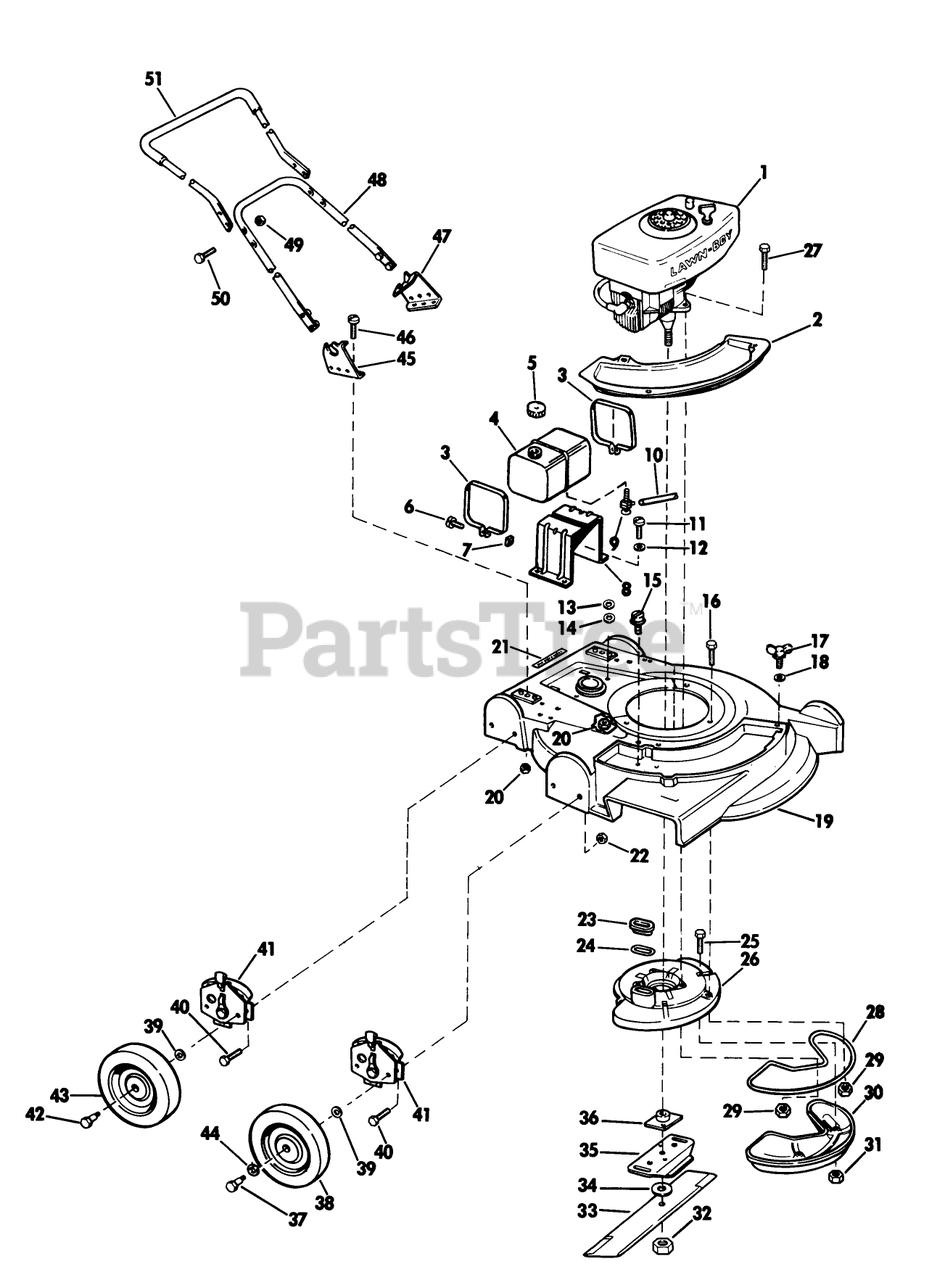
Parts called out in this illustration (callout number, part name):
9	VALVE&SCREEN SM
11	BOLT PIONEER
17	WING SCREW LAWRE
24	GASKET S
31	LOCKNUT E
32	NUT-BLADE
36	PLATE AND COLLAR ASM
37	BOLT WHEEL
39	WASHER WROUGHT
41	Height Adjustment Assy.
42	BOLT-SHOULDER
46	SCREW S
49	STOP NUT
